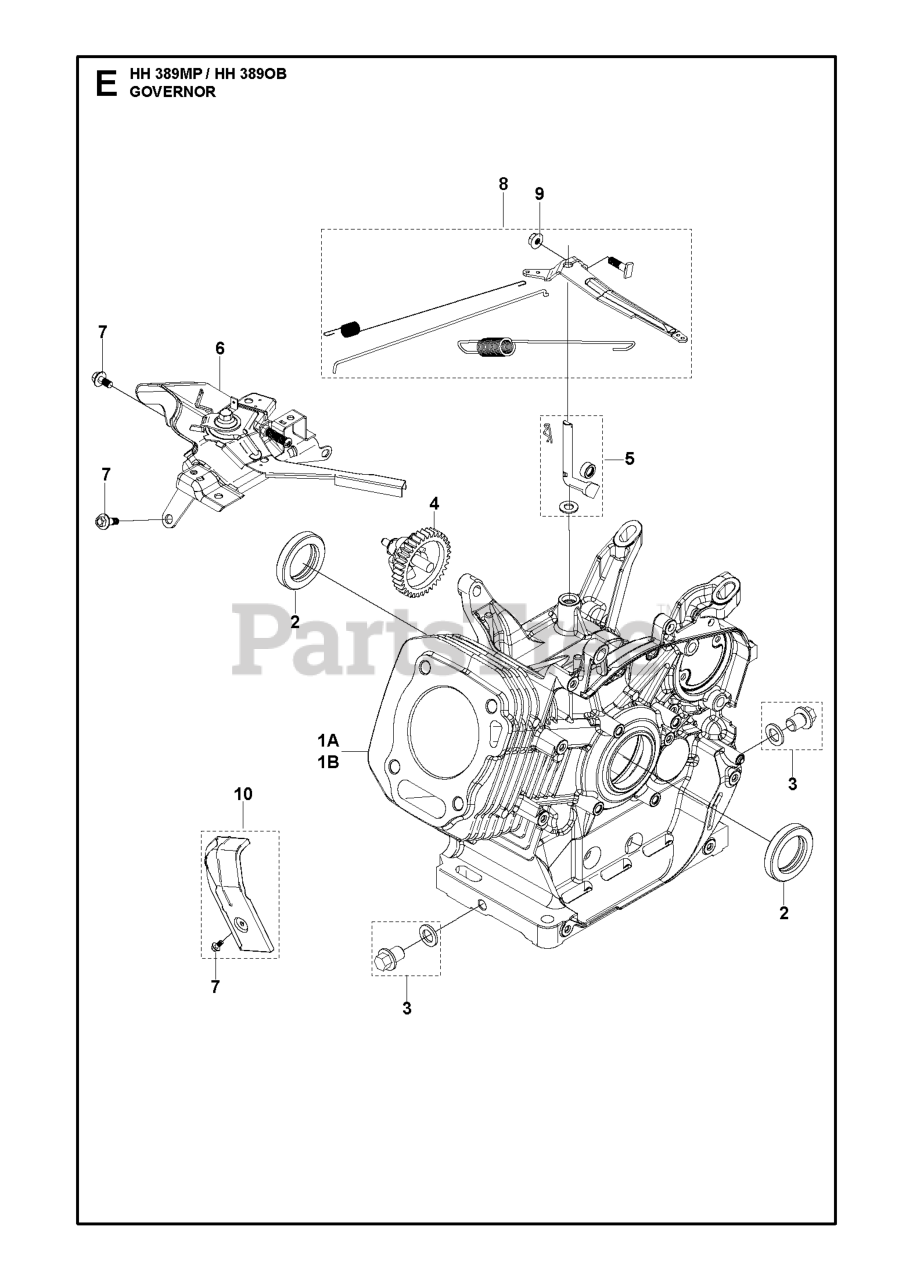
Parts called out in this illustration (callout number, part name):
2	SEAL OIL SEAL
7	Husqvarna TBD
9	NUT GB/T 6177.1: M6
